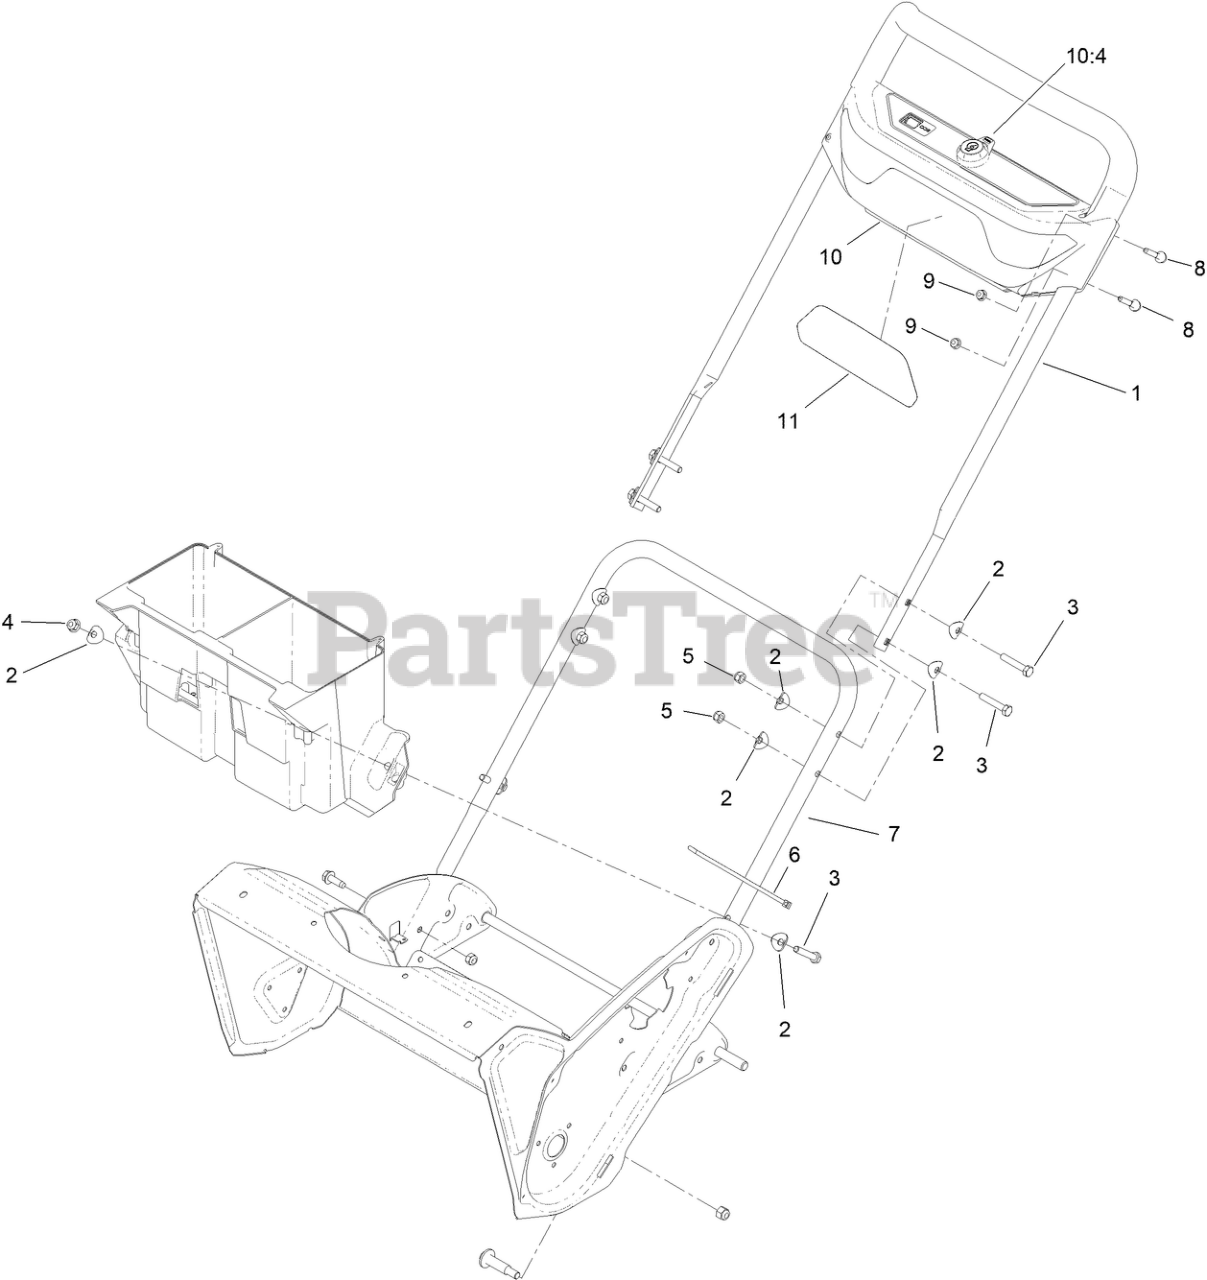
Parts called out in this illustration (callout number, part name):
1	HANDLE BAR-UPPER ASM
2	WASHER-CUP
3	SCREW-HH
4	NUT-FLANGE, NI
5	NUT-LOCK, NI
6	TIE-CABLE
7	HANDLE-LOWER
8	SCREW-HANDLE
9	NUT-HF
10	DASH PANEL ASSEMBLY, GENERIC SNOW
10:4	KEY-BAIL
11	DECAL - POWER CLEAR PRO
